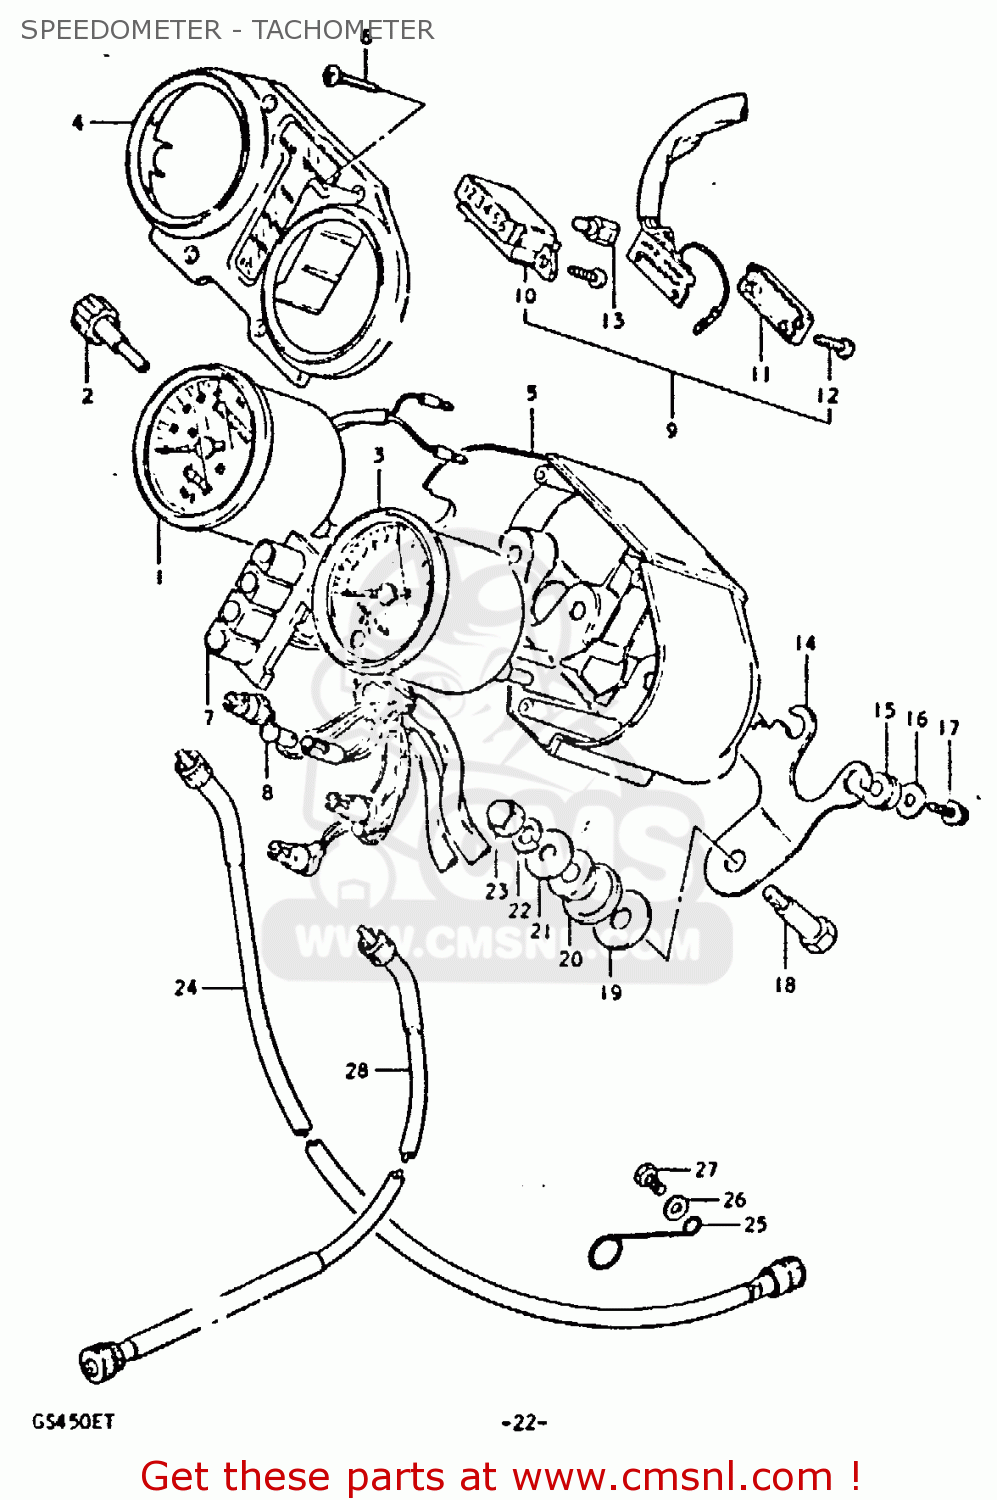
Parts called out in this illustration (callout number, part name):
1	METER,SPEEDOMETER (KM/MPH)
2	KNOB,TRIP METER
3	TACHOMETER
4	CASE,METER,UPPER
5	VISOR,LWR
6	SCREW
7	SOCKET,SPEEDOMETER
8	BULB(12V3.4W,STANLEY,A72A)
9	INDICATOR ASSEMBLY,GEAR POSITION
10	CASE,GEAR INDICATOR
11	COVER,LWR
12	SCREW,GEAR INDICATOR
13	BULB(14V1.12W)
14	BRACKET,METER
15	CUSHION
16	WASHER,METER
17	SCREW
18	BOLT(8X31)
19	WASHER
20	CUSHION,METER
21	WASHER(8.5X23X1.2)
22	LOCK WASHER
23	NUT
24	CABLE ASSEMBLY,SPEEDOMETER
25	GUIDE,SPEEDOMETER CABLE
26	WASHER
27	BOLT, UPPER
28	CABLE ASSEMBLY,TACHOMETER
